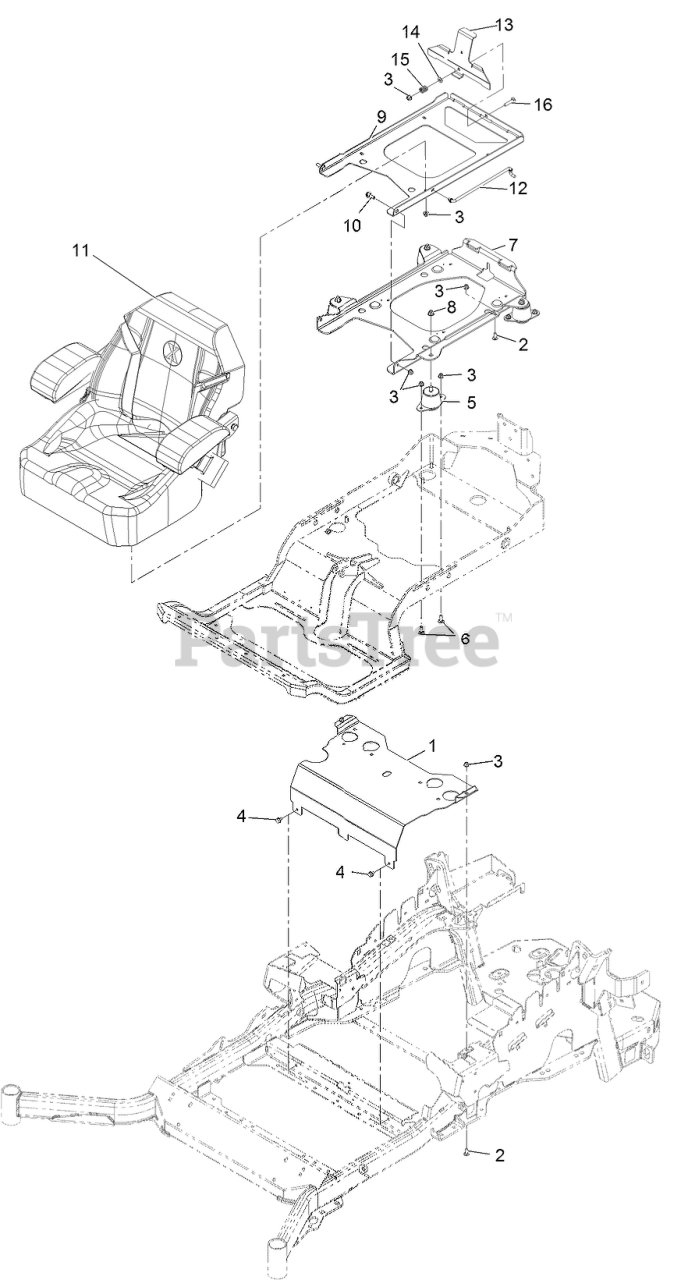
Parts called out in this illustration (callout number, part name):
1	Panel-Front, Seat Mount
2	SCREW-CARR
3	NUT-HF, NI
5	ISOLATOR-SEAT
6	BOLT-CARR
7	PLATE-SUPPORT, ISO SEAT
8	NUT-HF, NI
9	PLATE-FRAME, SEAT
10	SCREW-SHOULDER
11	SEAT-EXMARK STANDARD
12	ROD-PROP
13	PLATE-LATCH,SEAT
14	WASHER-PLAIN
15	SPRING-COMPRESSION
16	BOLT-CARR
